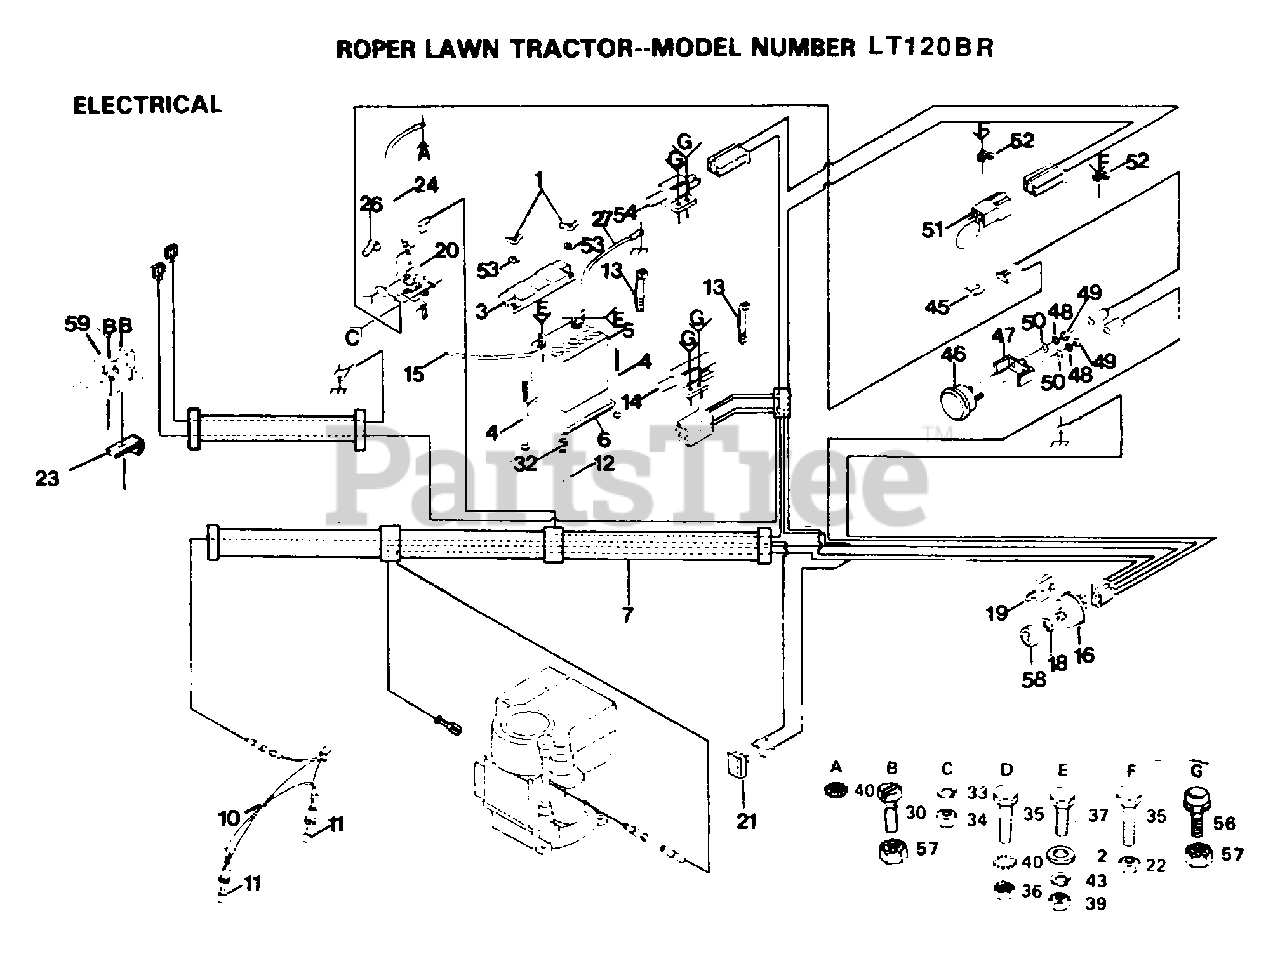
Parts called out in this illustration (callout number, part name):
2	WASHER
4	BOLT
6	"TRAY, BATTERY LT"
10	HARNESS T
13	WIRE TIE
14	SWITCH INTERLOCKT
15	"CABLE T, BATTERY"
21	SWITCH LT
27	CABLE ASSY LT
32	HOSE CLAMP T
34	NUT
35	BOLT
36	NUT
37	BOLT LT
43	LOCKWASHER
45	FUSE HYT
46	AMMETER T
50	WASHER
52	CLIPT
53	LOCKWASHER GT
54	SWITCH-INTER. GT
57	"NUT,KEPS"
